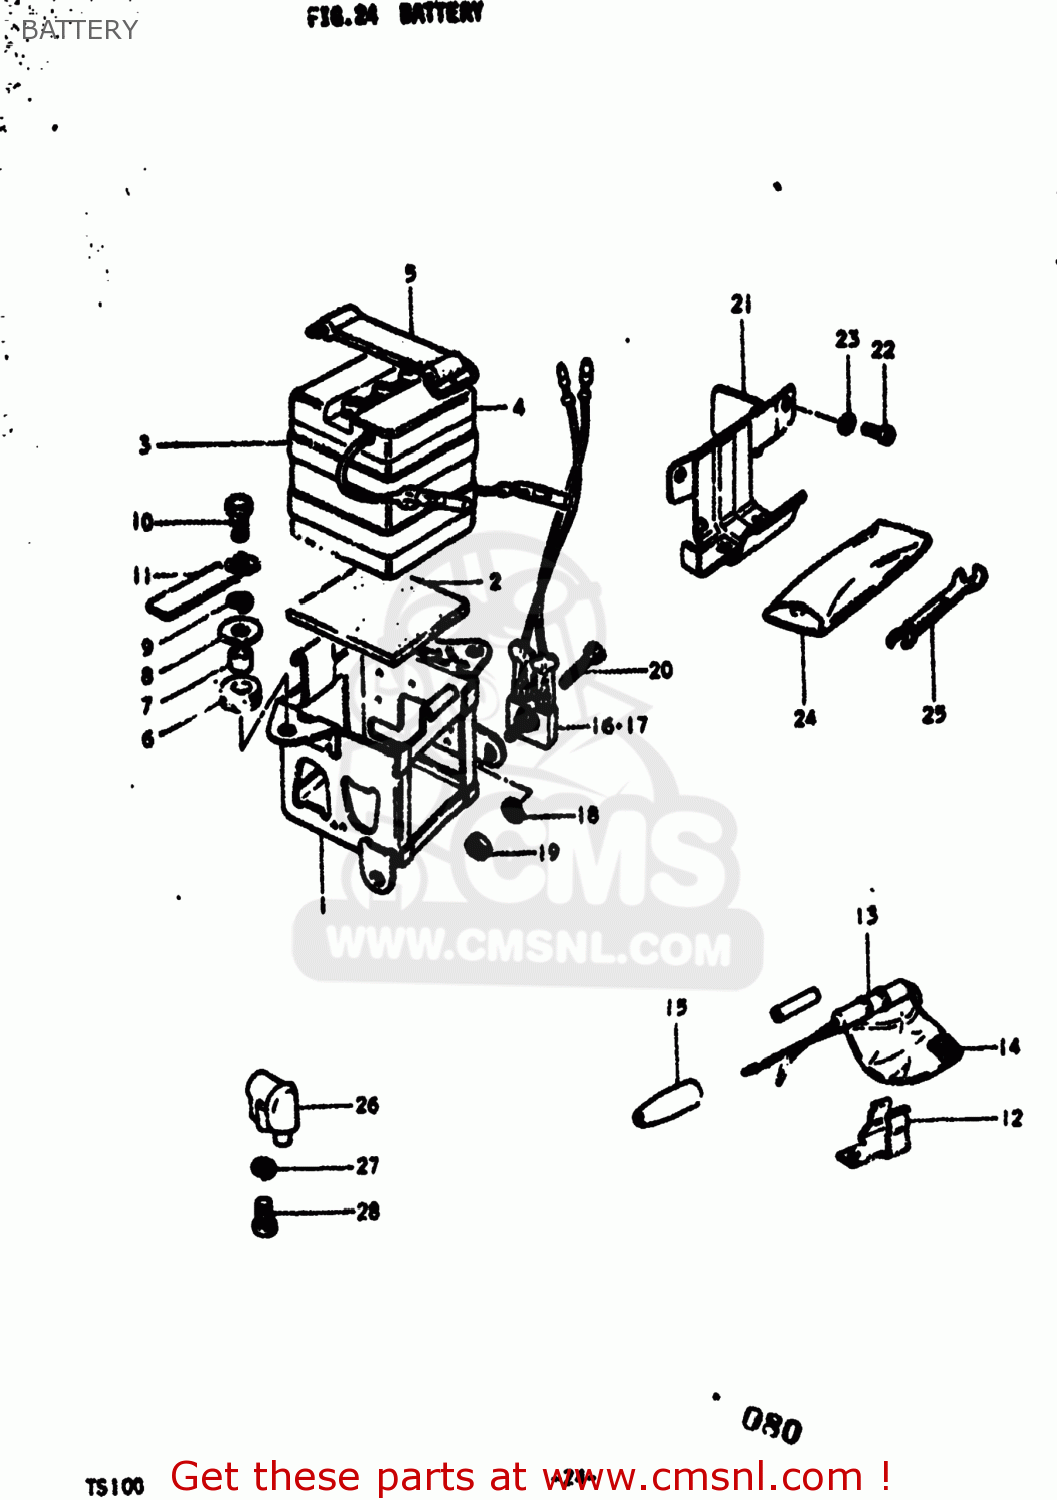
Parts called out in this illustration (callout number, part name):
1	HOLDER,BATTERY
2	CUSHION,BATTERY
3	PROTECTOR,BATTERY
4	BATTERY ASSY(6N4-2A4.2AH)
5	BAND
7	SPACER (7X9X7)
8	WASHER (6.5X20X1.2)
9	LOCK WASHER
10	BOLT
11	CLAMP
12	HOLDER,FUSE CASE
13	BOX ASSEMBLY,FUSE
14	FUSE(15A)
15	SEAL,DUST(10X17X45)
16	RECTIFIER ASSEMBLY
17	RECTIFIER ASSEMBLY
18	LOCK WASHER
19	NUT
20	SCREW
21	HOLDER,TOOL
22	SCREW 6X12
23	LOCK WASHER
24	TOOL SET
25	WRENCH, CONTACT POINT
26	LOCK ASSY,STEERING
27	LOCK WASHER
28	Screw
